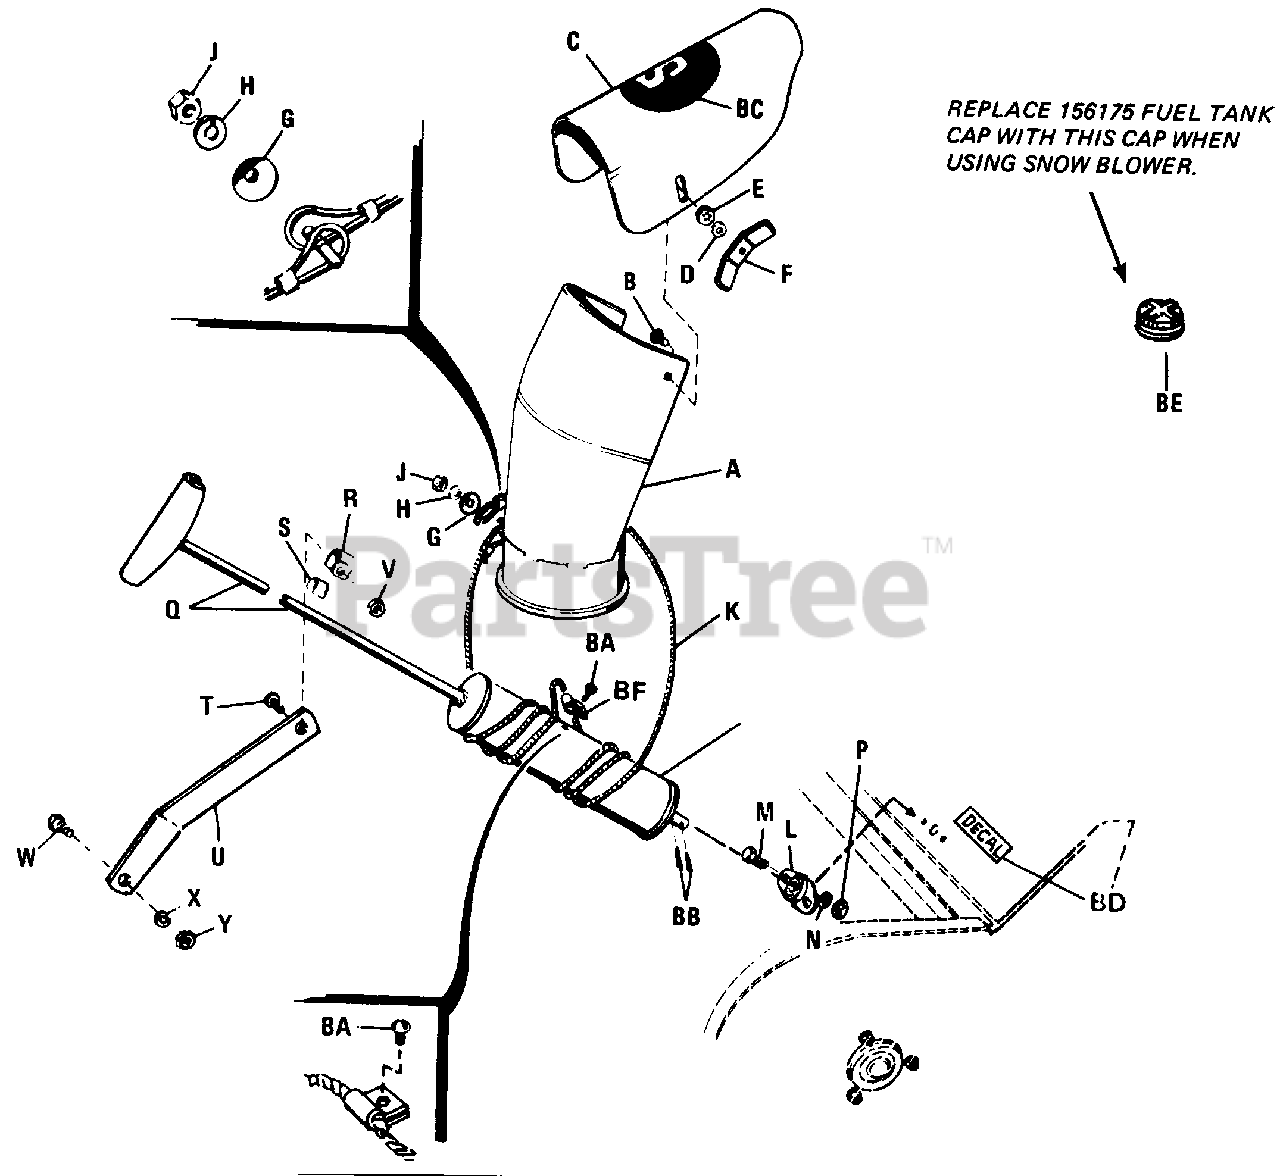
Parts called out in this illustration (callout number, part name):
A	Spout Assembly
B	Carriage Bolt, 5/16"-18 x 3/4"
C	Spout Extension
D	Plain Washer, 3/8"
E	Special Hex. Lock Washer, 3/8"
F	NUT, Wing, 5/16-18
G	Cup Washer
H	Lock Washer, 5/16"
J	Full Hex. Nut, 5/16"-18
K	Cable Assembly
M	Screw Hex Cap 16 1/4"-20 x 5/8" LG
N	Lock Washer, 1/4"
P	Full Hex. Nut, 1/4"-20
Q	Tube Assembly-Spout Control
S	Guide Liner
T	Hex. Capscrew, 5/16"-18 x 1-1/4"
U	Rod Guide Support
V	Full Hex. Lock Nut, 5/16"-18
W	Hex. Capscrew, 3/8"-16 x 1-1/4"
X	Lock Washer, 3/8"
Y	Hex. Nut, 3/8"-16
BA	Self-Tapping Screw, 1/4-20 x 3/8" lg.
BB	Cotter Pin, 3/32" x 5/8"
BD	Safety Decal
BE	Cap-Fuel, Tank
BF	Clamp (For Service Only)
